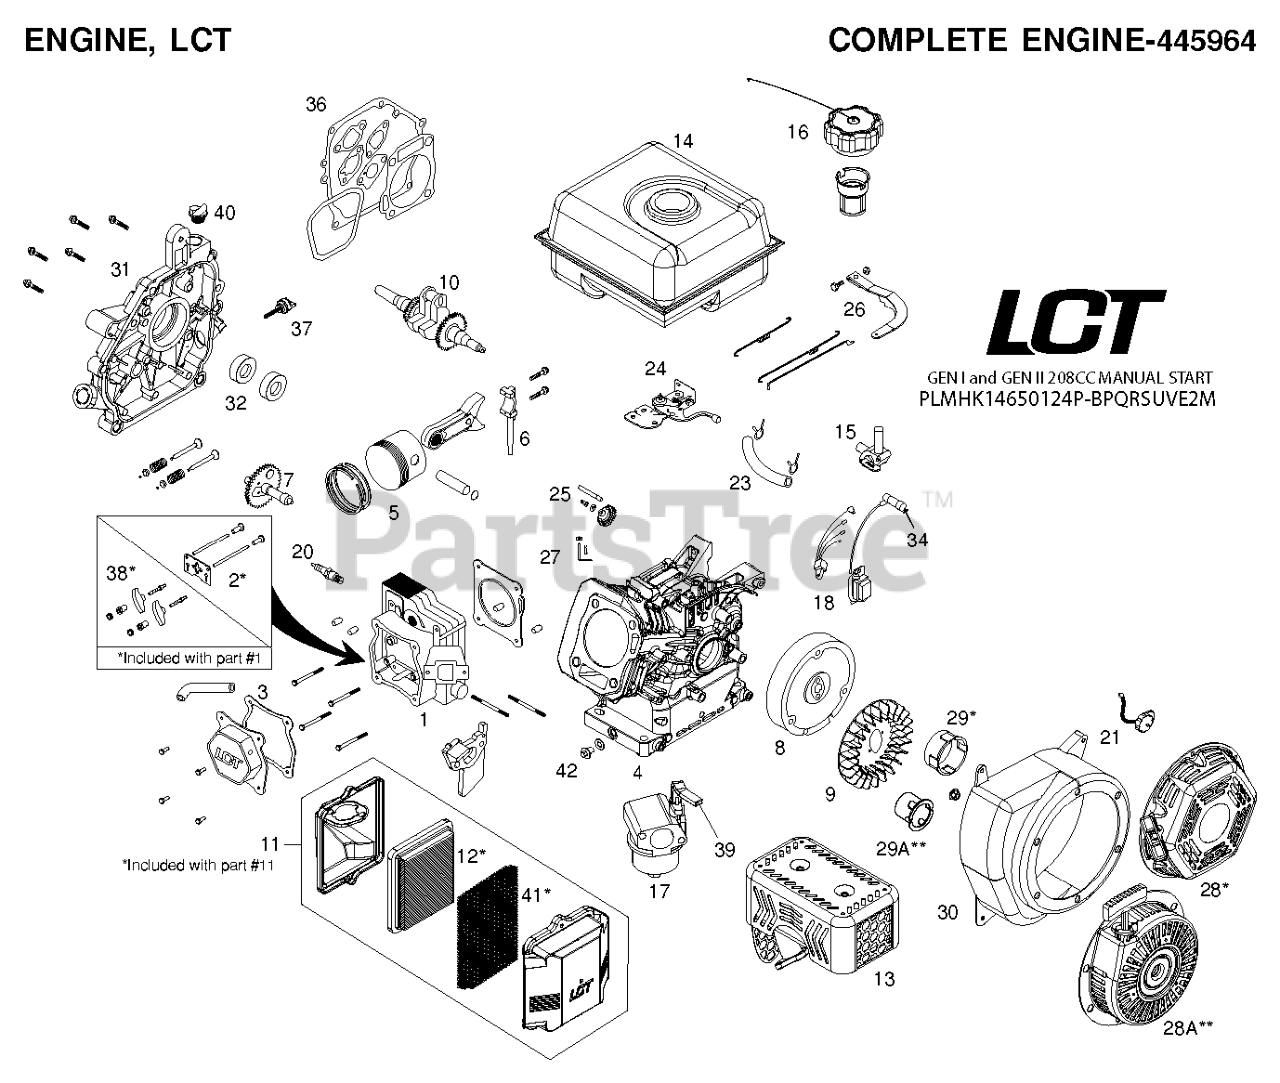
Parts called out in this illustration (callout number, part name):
1	CYLINDR.HEAD.SRV.KIT W/GASKET
2	KIT.PUSH.ROD.SRV(SK208-1001)
3	VALVE COVER ASSEMBLY
5	KIT.PISTON.SRV(SK208-1400)
6	KIT.CONNECT.ROD.SRV(SK208-1500
7	KIT.CAMSHAFT.208CC.LCT
8	FLYWHL.ASSY.MANUL.SK2081700
9	FLYWHEEL FAN 420586
10	CRANKSHAFT-KEYED(SK2081800.1)
11	KIT.AIRFLTR.ASY.SRV(SK208-2002
12	FILTER.ASSEM.PANEL.LCT.208CC
13	KIT.49STATE.MUFFLER(SK208-2101
15	FUEL.PETCOCK.1/4".LCT
16	FUEL CAP OVERSIZED CLICK STYLE
17	KIT.CARBURETOR.SERV(SK20-2401)
18	KIT.IGNITION.COIL
20	SPARK.PLUG(2083810)
21	KIT.ENGINE.ON/OFF.LCT.208CC
23	FUEL HOSE KIT
24	THROTTLE CONTROL ASSEM
25	GOVENOR.GEARS ASM(SK2082900)
26	RP_IT.GOVERNOR.ARM(SUMMER ENG)
27	KIT.GOVERNOR.CRANK(SK208-3100)
28	KIT.RECOIL.STARTER(HEX) BLACK
28A	RECOIL.STARTER.ROUND.BLACK
29	KIT.STARTER.CUP.SRV(SK208-3300
29A	START.CUP.NON-SLOTTED
30	KIT.BLOWER.HSG.SRV(SK208-3400)
31	COVER.CRANKCASE.LCT.HIGH.OIL.F
32	SEAL KIT (2 PCS)
34	SPARK.PLUG.BOOT(SK2083800)
36	GASKET.KIT.208CC(SK2084300.1)
37	DIPSTICK SMALL
38	ROCKER ARM KIT
39	CHOKE LEVER.CARB.LCT.208CC
40	NON REMOVABLE PLUG
41	FOAM.PRE.FILTER.LCT.208CC
42	KIT.OIL.DRAIN.PLUG(SK2089911
